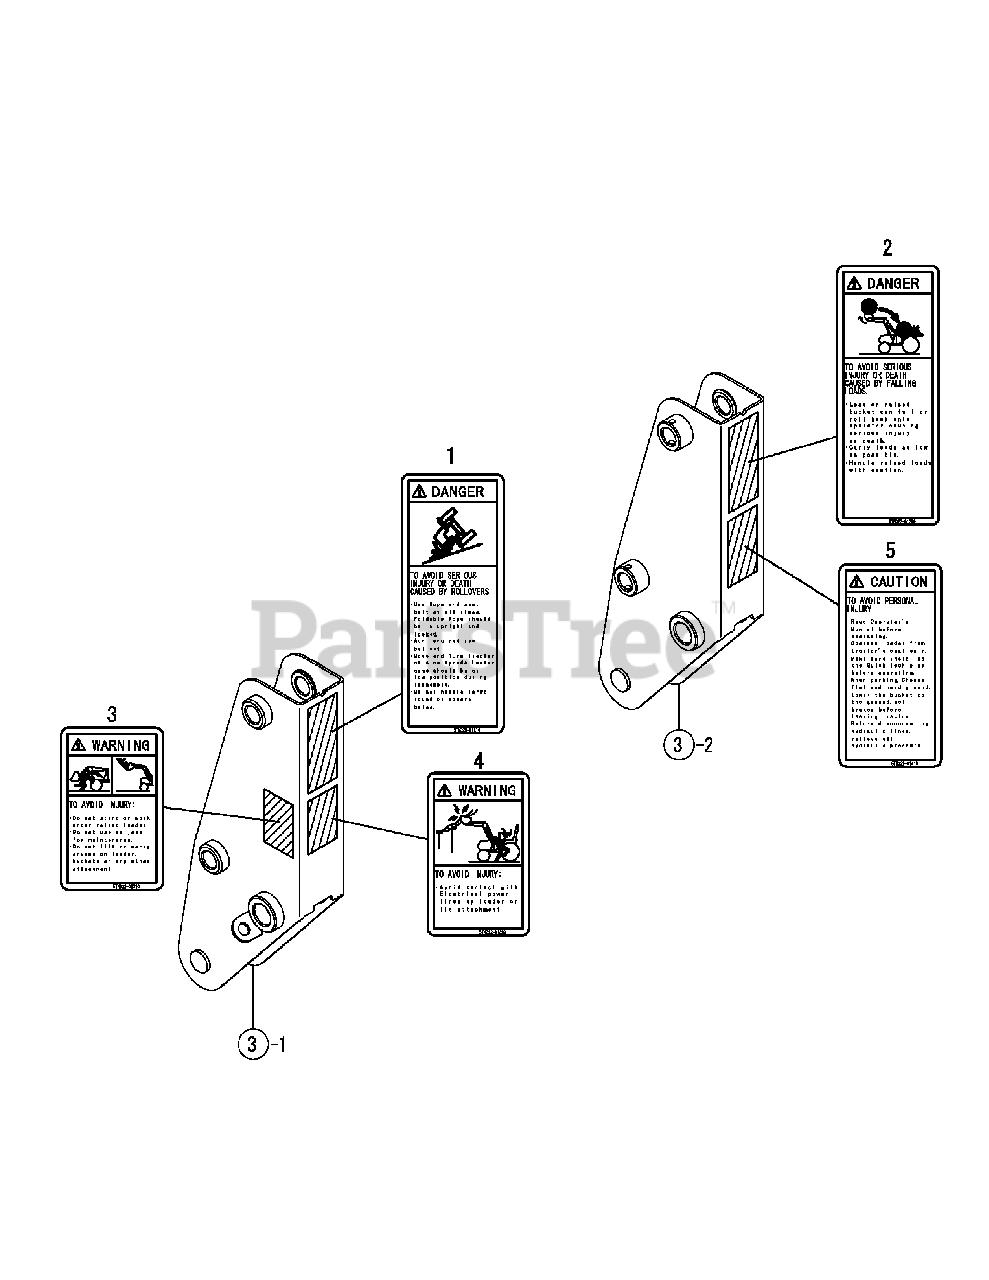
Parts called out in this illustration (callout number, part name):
1	LABEL,DANGER,ROLL
2	LABEL,DANGER,FALL
3	LABEL,WARNING
4	LABEL,WARNING,SHOCK
5	LABEL,CAUTION
